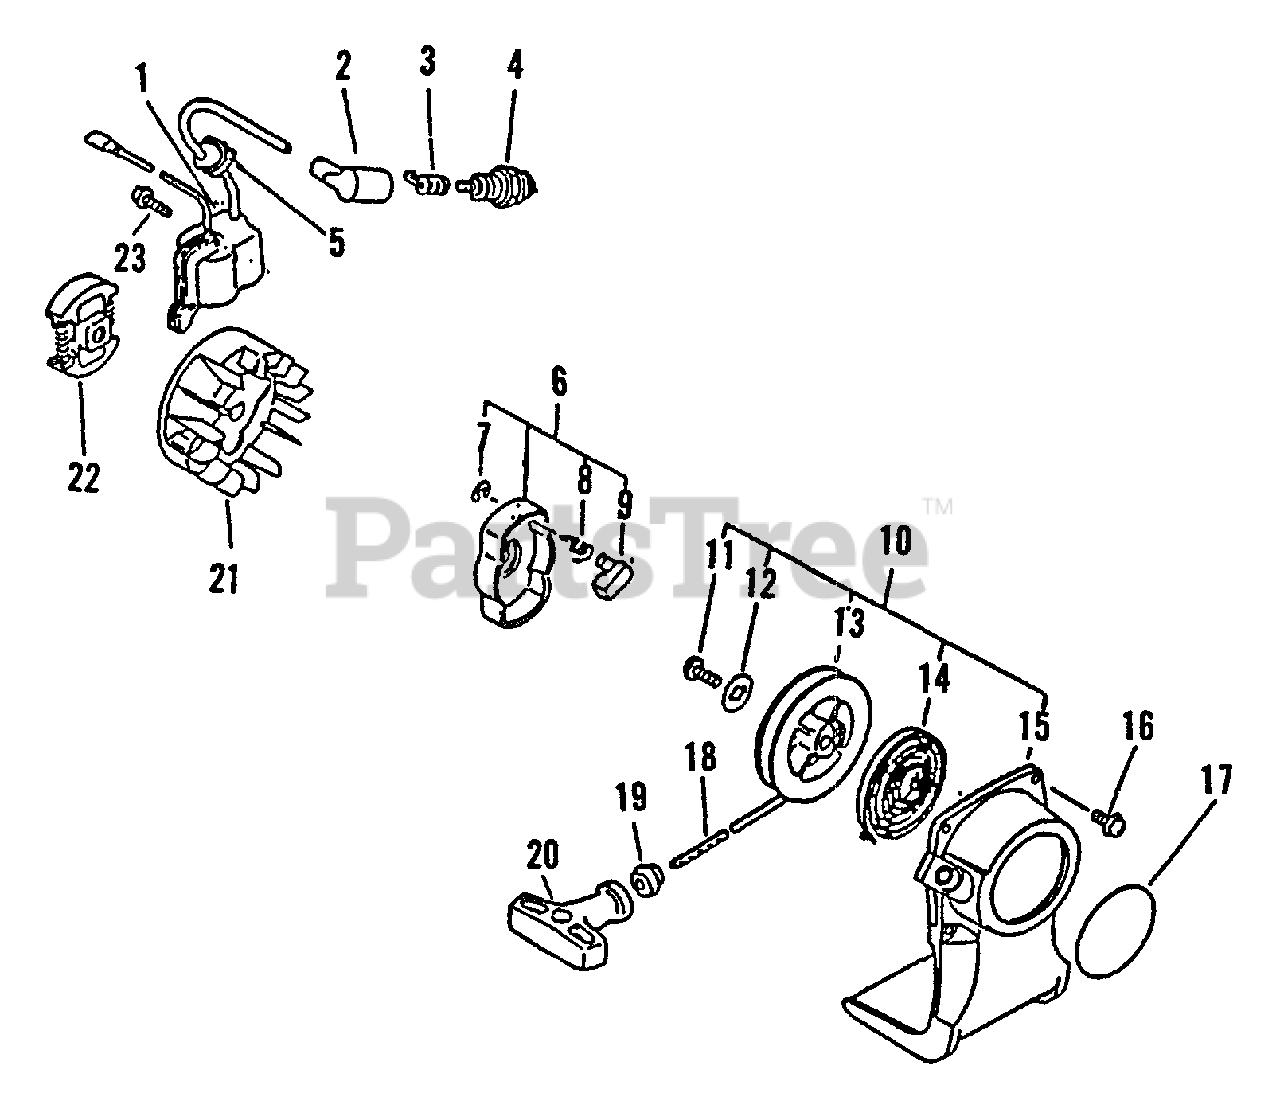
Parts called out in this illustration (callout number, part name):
1	Coil, Ignition
2	Cap, Spark Plug
3	Coil, Spark Plug Cap
4	Plug, Spark BPM-7A
5	Grommet, H.T. Cord
6	Pawl Asy, Starter
7	E-ring 4
8	Spring, Return
9	Pawl, Starter
10	Starter Asy
12	Washer
13	Drum, Starter
14	Spring, Rewind
15	Case, Starter
16	Screw 4x16
17	Label, Brank
18	Rope, Starter
19	Guide, Rope
20	Grip, Starter
21	Flywheel
22	Clutch Asy
23	Screw 4x22
